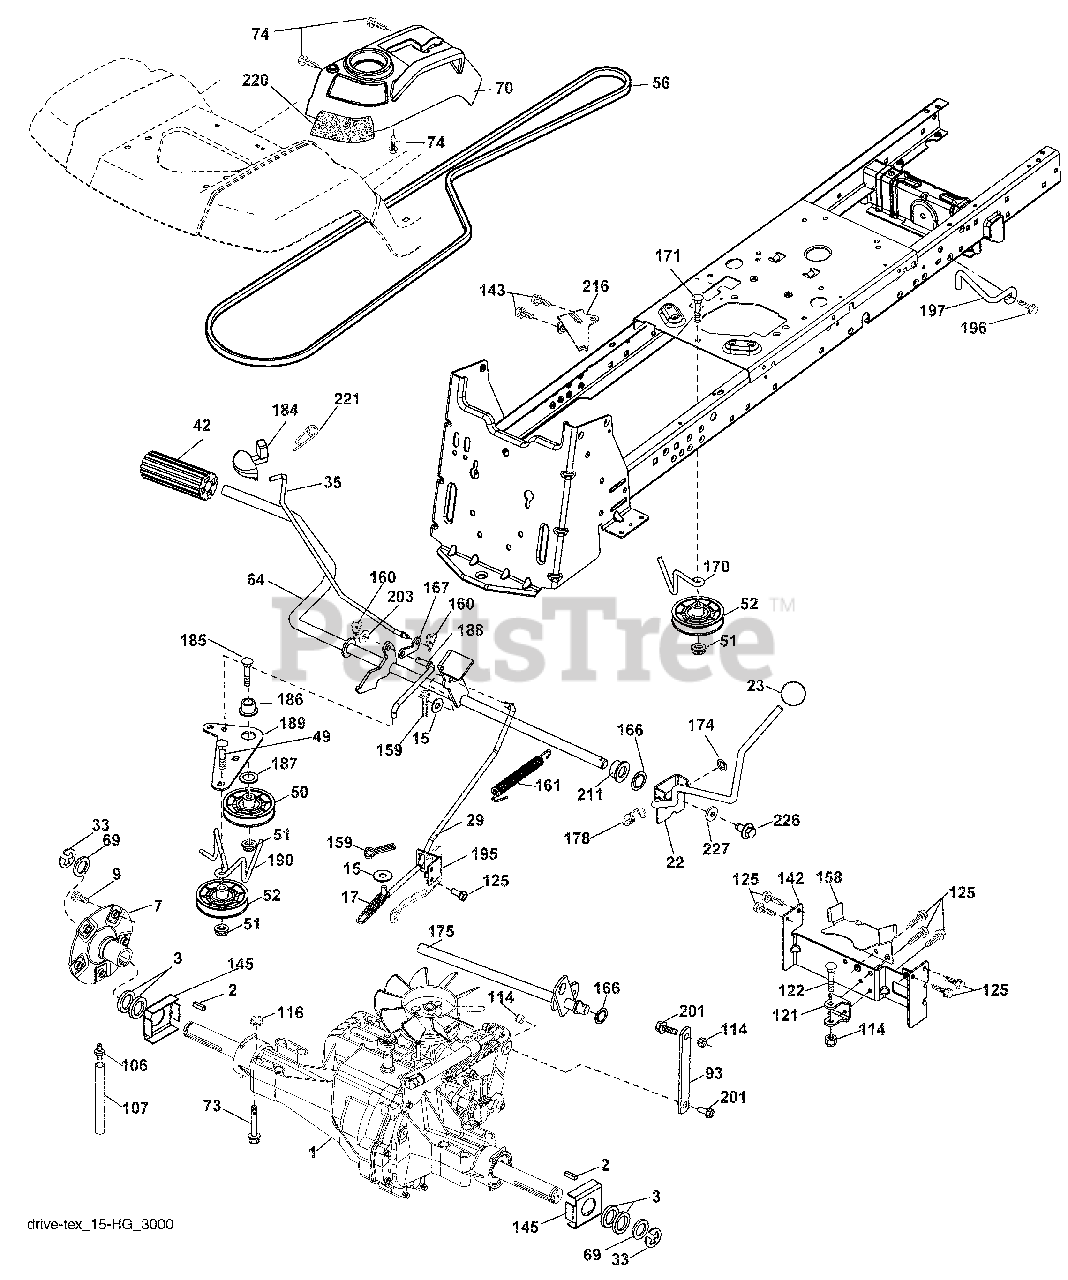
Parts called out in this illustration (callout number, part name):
2	Key 1/4 x 2.5
7	Hub Asm. Wheel
9	Bolt Hub Wheel
15	Washer 13/32 x 13/16 x 16 Ga.
17	Spring, Brake
22	Shifter Rod
29	Rod, Brake
35	Rod, Brake, Park
42	Cover, Foot Pedal
50	Pulley Idler Flat
51	Lock Nut 3/8-16
52	Idler V-Groove 910" Offset
56	V-Belt, Drive
64	Shaft Asm. Pedal Brake Control
69	Washer 11/32 x 1-5/8 x 16 Ga.
70	Control Asm.
73	Bolt Hex Flghd 5/16-18 x 3.00
74	Screw 1/4 x 1/2
93	Link Shift
106	Cap Asm. Vent
114	Nut Lock Hex w/Insert 5/16-18 unc
116	Nut Lock Hex Flange 5/16-18
121	Bracket Strap Torque
122	Bolt 5/16 - 18 x 2.50
125	Screw 5/16-18 x 3/4
142	Strap Torque
143	Screw Thdrol 5/16-18 x 1/2
145	Washer Axle flange
158	Keeper Belt
159	Pin Cotter 1/8 x 3/4
160	Retainer Clip
161	Spring, Return, Clutch
166	Nut Push .625
167	Latch Brake Parking
170	Keeper Belt Centerspan
175	Shaft Asm Shift
178	Spring Shift
184	Handle Parking Brake
185	Bolt Rdhd Sqnk 3/8-16 x 2-1/2
186	Spacer Retainer
187	Washer
188	Link Clutch Ground Drive
189	Bellcrank Ground Drive
190	Keeper Bellcrank Ground Dr.
195	Bracket Rod Brake
196	Screw 3/8-16 x 1
197	Bracket Clutch Anti-Rotation
200	Nut Center Lock 5/16-18
201	Bolt Shoulder 5/16-18 unc
203	Washer 11/32 x 11/16 x 16 Ga.
216	Bracket Pulley Idler
220	Reflector RH
221	Retainer Spring Clip Handle
226	Bolt Fin Hex 7/16 - 14 x 1 GR5
227	Washer Serrated
